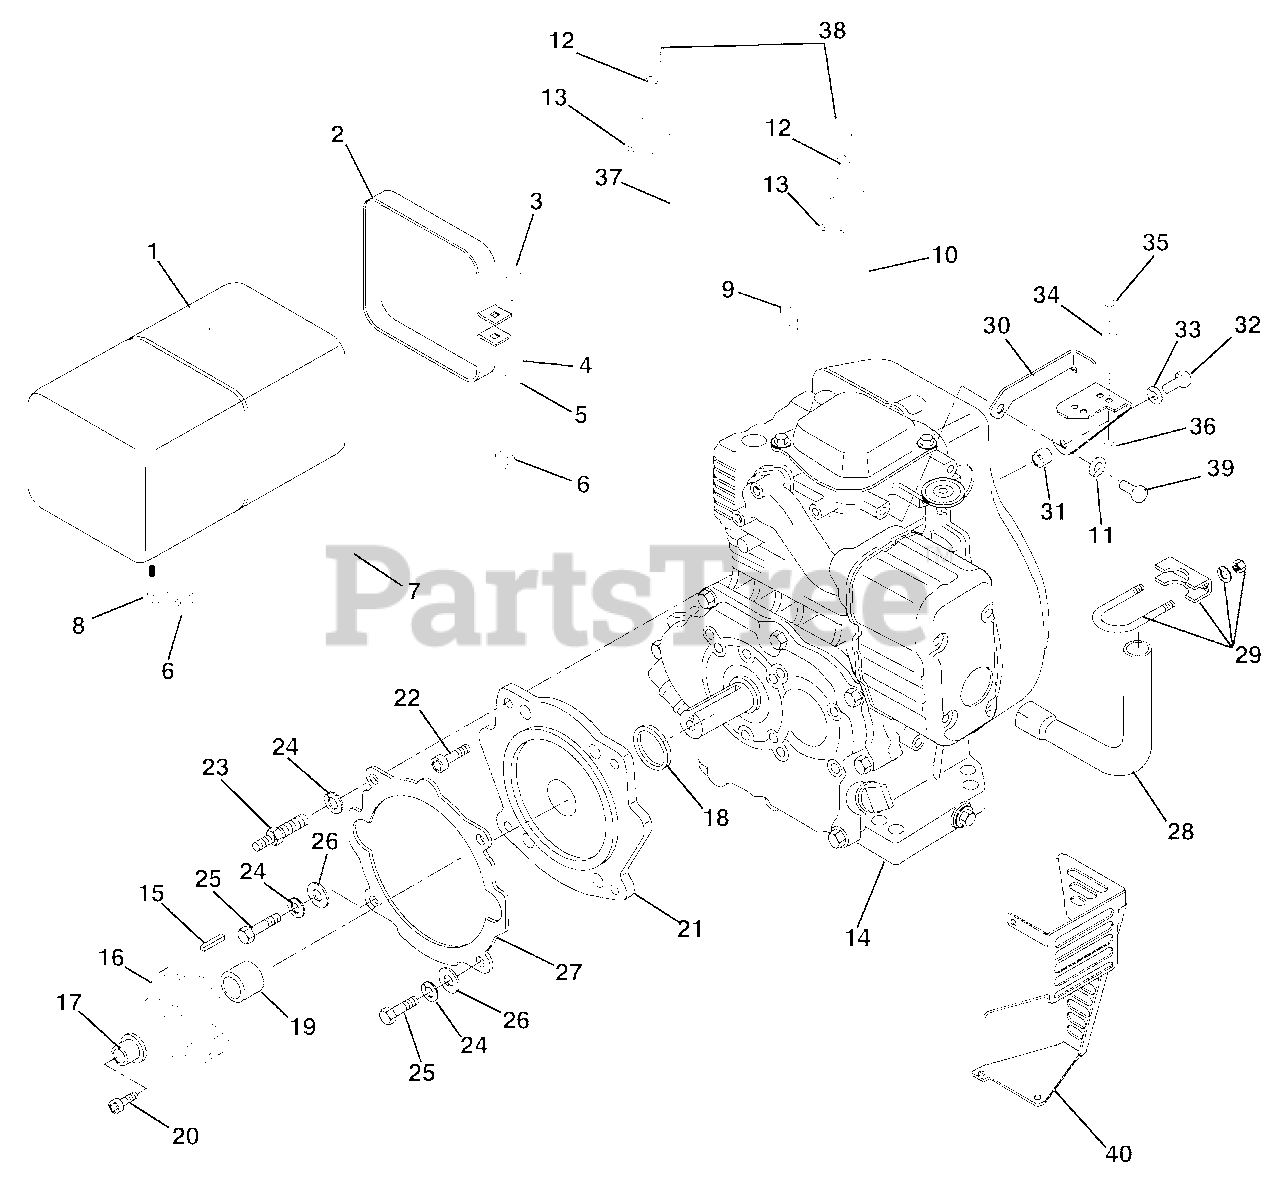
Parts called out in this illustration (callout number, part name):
1	Tank,Gas with Cap
2	Strap-Fuel Tank
3	Bolt-Round Head Square Neck .25-20 x 1.75
4	Washer-Flat-Steel .281 x .620 x .065
5	Nut-Locking-Center .250-20 Grade 2
6	Clamp-Hose
7	Gas Line-Bulk
8	Valve & Strainer
9	Clamp
10	Cable-Control (Throttle)
11	Washer-Locking .31 x .078 Regular
12	Screw-Machine 10-24 x .50
13	Nut-Locking Nylon 10-24
14	Engine-8HP Robin
15	Key-Square .248 x 1.0 x .248
16	Gear
17	Pilot-Gear
18	Seal 1.188 x 2.000 x .250
19	Spacer-Steel 1.00 x 1.31 x .836
20	Screw-Machine .38-24 x 1.00
22	Screw-Socket Head .38-16 x 1.00
23	Stud
24	Washer-Lock .438 x .133
25	Bolt-Hex .44-14 x 1.50
26	Washer-Flat-Steel .469 x .938 x .065
27	Gasket-Chassis to Adapter
28	Elbow
29	Clamp-Muffler 1.25
30	Bracket-Cable Mount
32	Bolt-Hex M6 x 1.00 x 20
33	Washer-Locking .25 x .062 Regular
34	Clip-Cable
35	Screw-Machine Hex Washer Head 10-24 x .75
36	Nut-Locking-Nylon 10-24 w/ Insert
37	Cable-Control (Choke)
39	Bolt-Hex M8 x 1.25 x 16
40	Muffler Guard (307)
